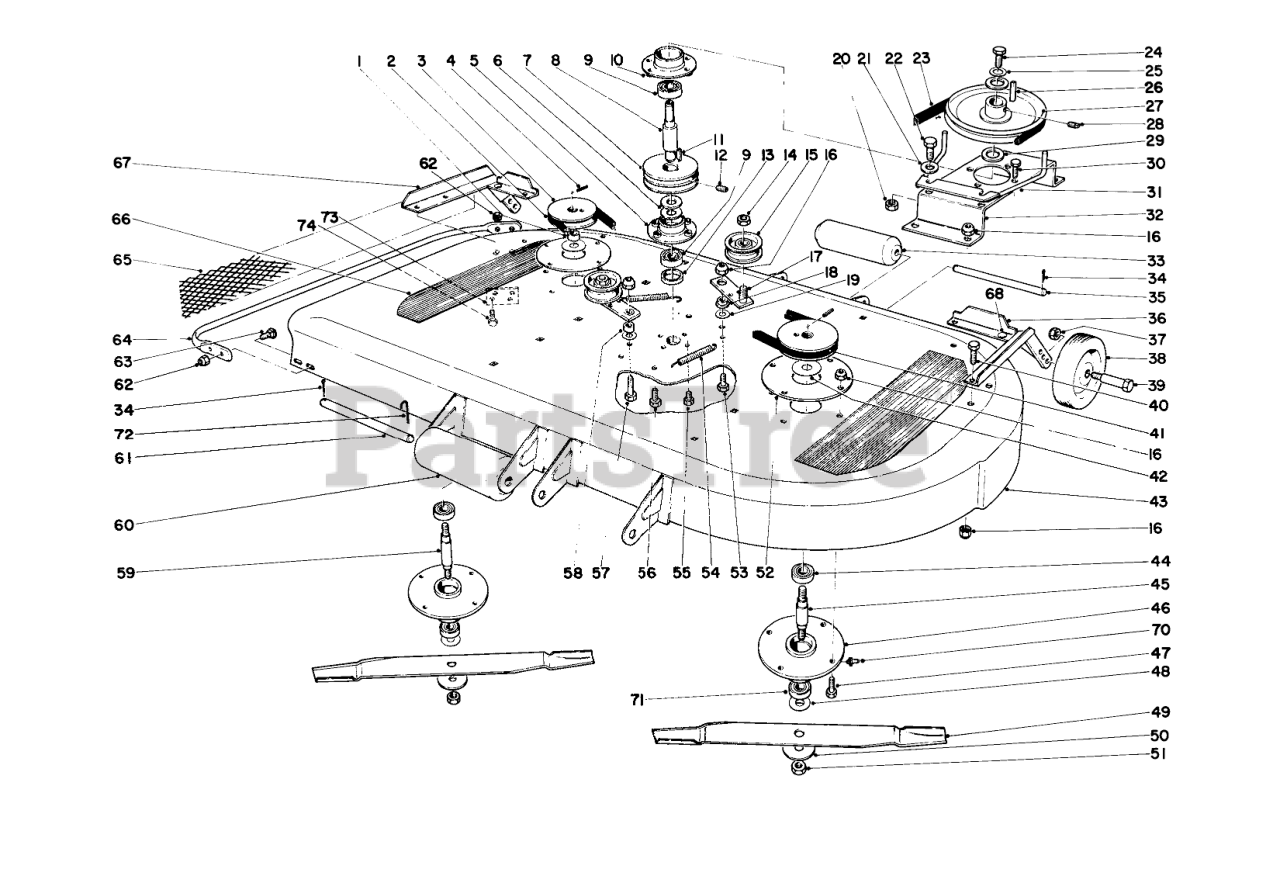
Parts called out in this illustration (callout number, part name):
1	Spacer
2	Belt
3	Pulley
4	ROLL PIN
5	Bearing Housing
6	Washer
7	Pulley
8	BLADE DRIVE SHAFT
9	Bearing
10	Bearing Housing
11	KEY-WOODRUFF
12	Set Screw
13	Spacer
14	NUT-JAM
15	PULLEY-IDLER
16	NUT-LOCK, CONE
17	Idler Arm
18	Bushing
19	WASHER-FLAT
20	NUT-LOCK, CONE
21	WASHER-FLAT
22	SCREW-HH
23	V-BELT
24	SCREW-HH
25	Washer
26	KEY-SQUARE
27	Pulley
28	Set Screw
29	Washer
30	Sems Screw
31	Belt Guide
32	Support
33	Roller
34	PIN-COTTER
35	ROLLER SHAFT
36	Bracket
37	NUT-LOCK, CONE
38	Wheel
40	SCREW-HH
42	Washer
43	Housing
44	Bearing
45	LH BLADE SHAFT
46	MOWER SPINDLE HOUSING
47	SCREW-HH
48	WASHER
49	Blade
50	WASHER
51	NUT-LOCK, CONE
52	Washer
53	SCREW-HH
54	IDLER ARM SPRING
55	1/4-20 X 3/8 SEMS SCR
56	SCREW-HH
57	SCREW-HH
58	Spacer
59	Blade Shaft
60	Roller
61	ROLLER SHAFT
63	SCREW-CARR
64	Guard
65	Mulcher
66	Foot Pad
67	Bracket
68	Plug Button
70	FITTING-GREASE
71	.6693 RP BALL BEARING
72	Retainer Roller
73	Bracket Blade Guard
74	SCREW-HH
